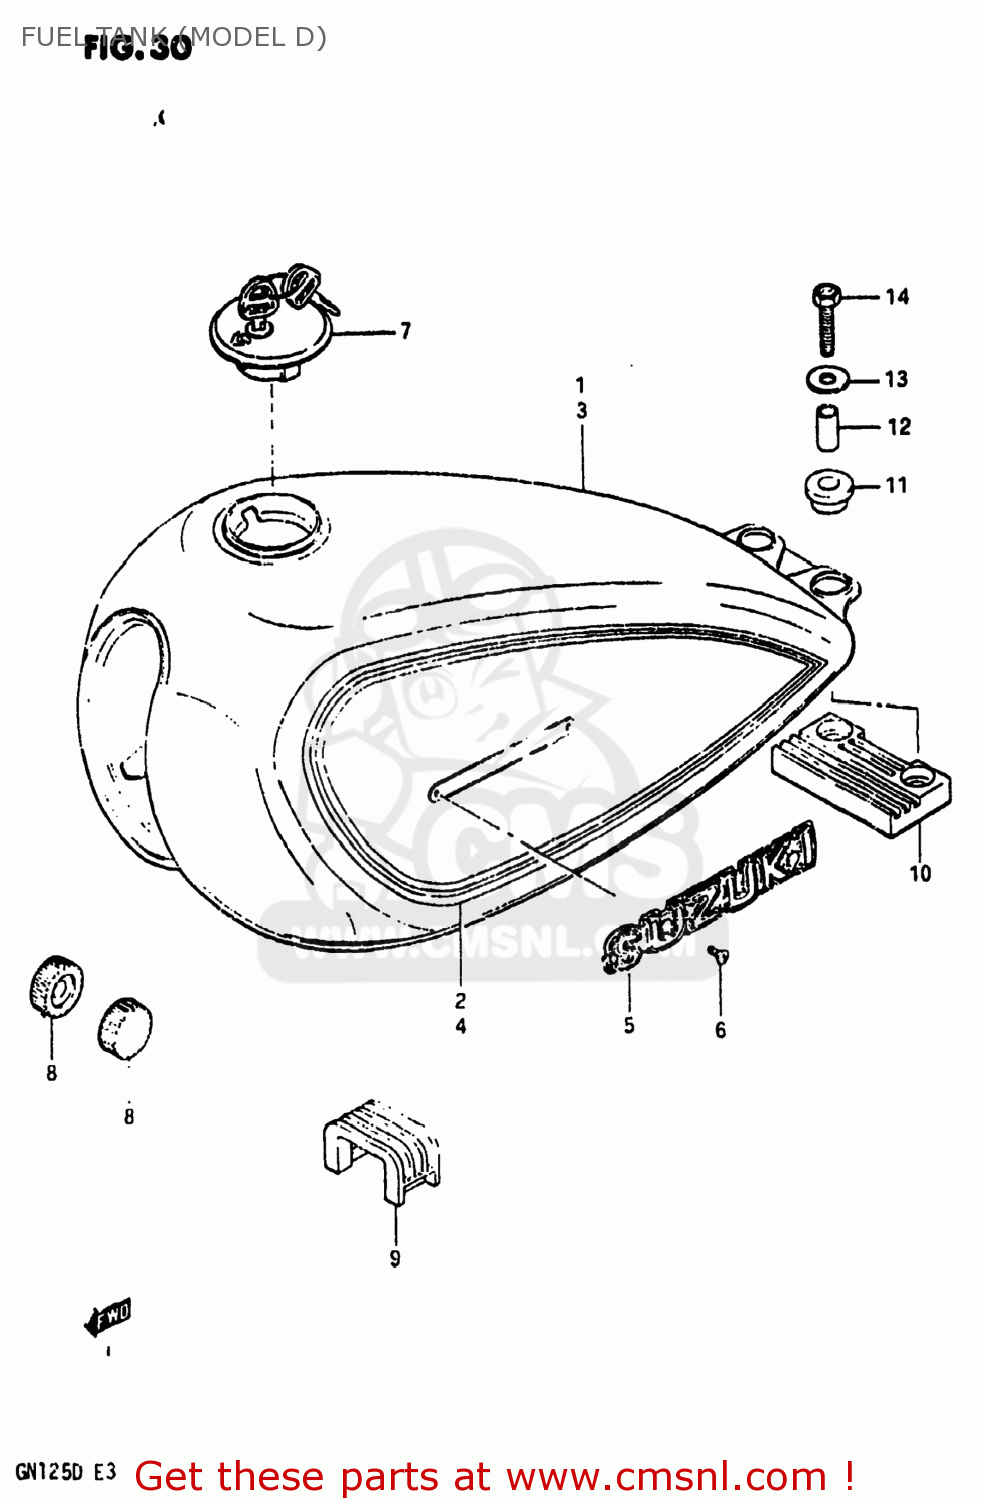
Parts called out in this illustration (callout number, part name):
1	TANK ASSEMBLY,FUEL
2	TAPE SET,FUEL TANK
3	TANK ASSEMBLY,FUEL
4	TAPE SET,FUEL TANK
5	EMBLEM,FUEL TANK
6	SCREW 3X6
7	CAP SET,FUEL TANK
8	CUSHION
9	CUSHION,FUEL TANK UPR FR
10	CUSHION,TANK RR NO.1
11	CUSHION
12	SPACER(6.5X10.5X22.5)
13	WASHER(6,5X22X1.6)
14	BOLT(6X35)
